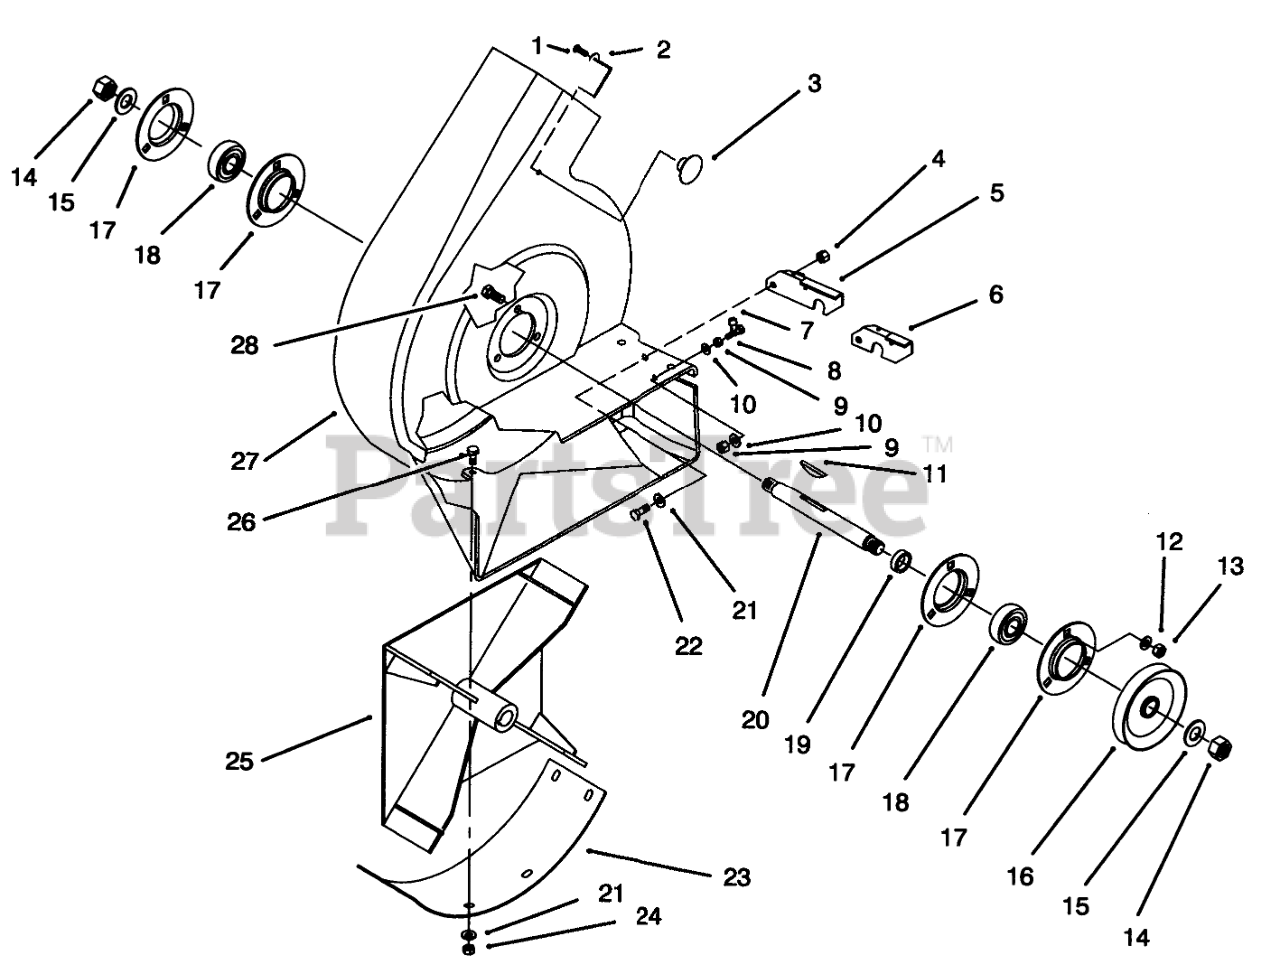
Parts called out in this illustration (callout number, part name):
1	SCREW-PPHTF
2	WASHER-PLAIN
4	NUT-LOCK, NI
5	48" BLOWER LATCH B
6	42" BLOWER LATCH B
7	SPRING-EXTENSION
8	SCREW-HWH
9	NUT-HEX
10	WASHER-FLAT
12	WASHER-LOCK
13	NUT-HEX
14	NUT-JAM
15	WASHER-LOCK
16	PULLEY-BLOWER
17	FLANGE
18	BEARING-BALL
19	Spacer
20	SHAFT-BLOWER
21	WASHER-FLAT
22	SCREW-HH
23	COVER-BLOWER, BOTTOM
24	NUT-LOCK, NI
25	Impeller
26	SCREW-CARRIAGE
27	HOUSING-VAC, BLOWER
28	SCREW-CARR
